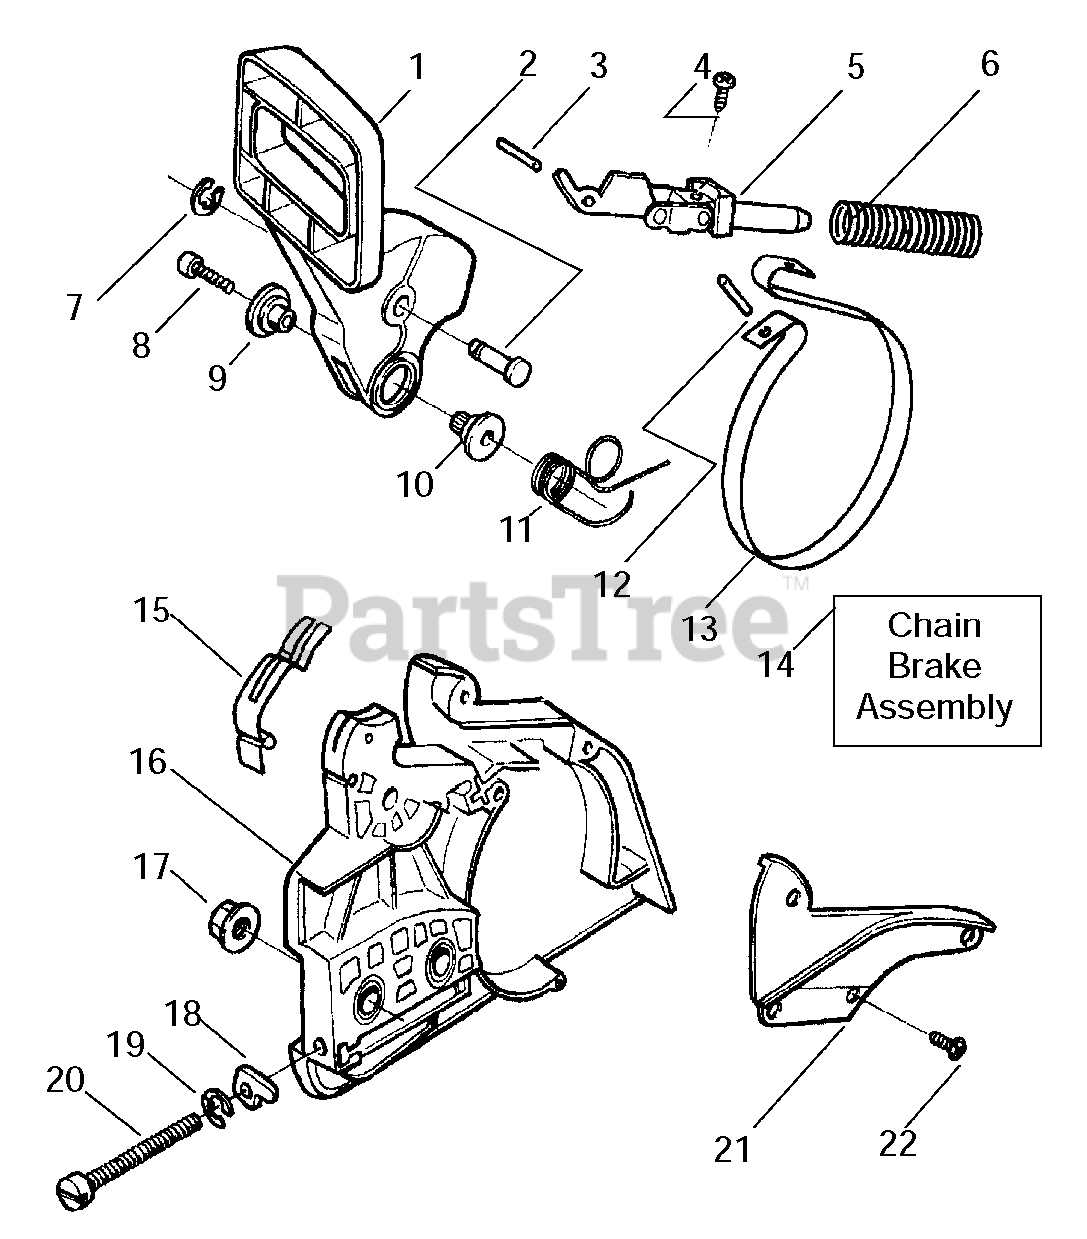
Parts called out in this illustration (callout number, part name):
4	SCREW
5	FRONT LINK ASSY
6	%COMPRESSION SPRING
9	JOURNAL, RIGHT
10	SHAFT PIVOT
11	SPRING,BRK HDL 36/41
13	BRAKE BAND
14	CHAIN BRAKE ASM.
15	SPRING-POSITION
16	CLUTCH COVER
18	ADJUST PIN,BAR 36/41
20	BAR ADJUSTING SCREW
21	CHAIN BRAKE COVER
22	SCREW
